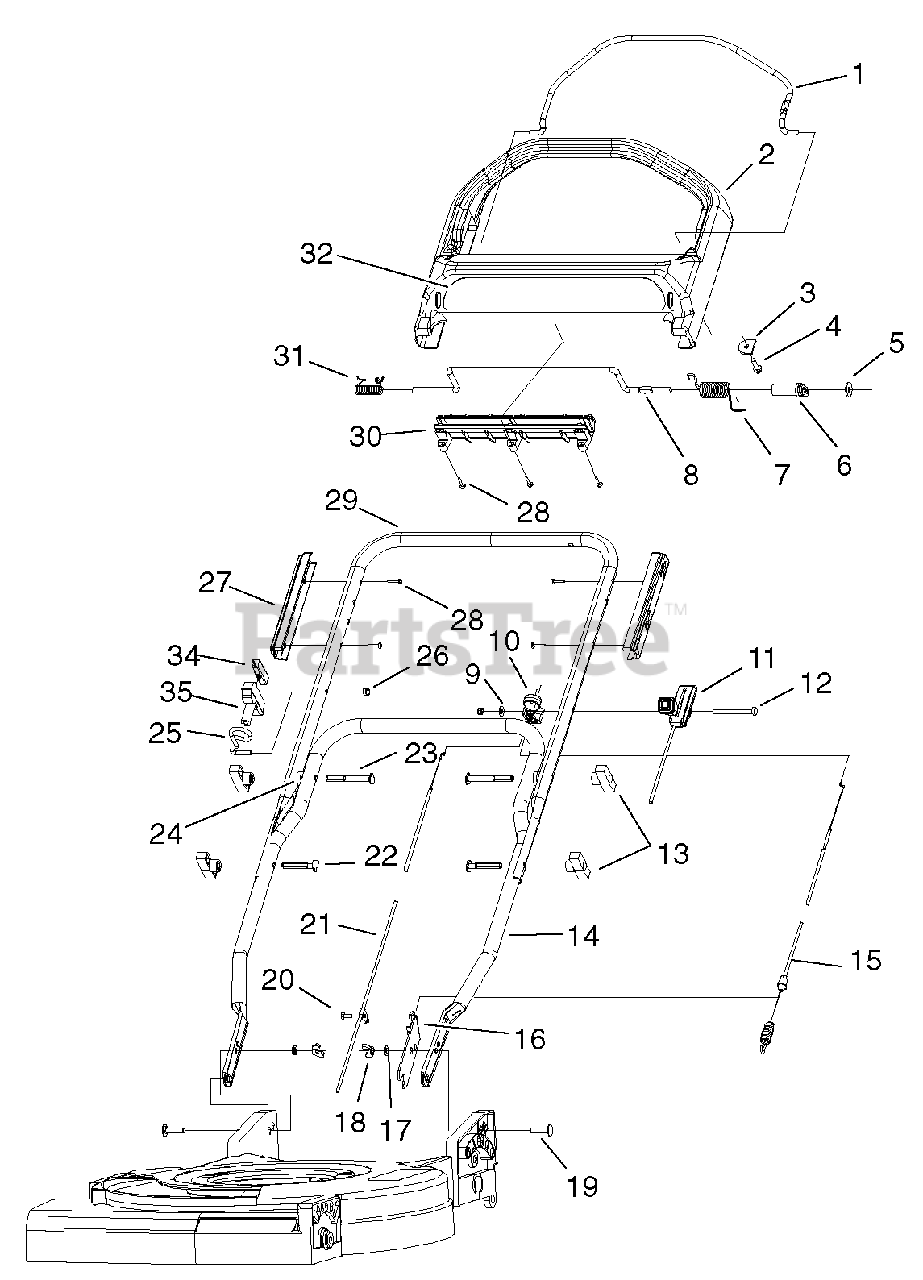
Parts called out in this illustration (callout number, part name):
1	BAIL-BRAKE
2	HANDLE-CONTROL
3	RETAINER-CABLE, BRAKE
4	SCREW-HWH
5	WASHER-FLAT
6	LEVER-TRACTION
7	SPRING-TORSION
8	BAR-CONTROL, TRACTION
9	WASHER-FLAT
10	ANCHOR-CABLE
11	CABLE - THROTTLE
12	SCREW-HH
13	KNOB-HANDLE
14	HANDLE-LOWER
15	CABLE-TRACTION
16	BRACKET-CABLE, TRACTION
17	WASHER-LOCK
19	SCREW-CARR
20	SCREW-TAPTITE
21	CABLE-BRAKE, FLYWHEEL
23	SCREW-HANDLE
24	SPACER-HANDLE
25	GUIDE-ROPE
26	NUT-LOCK, NI
27	GUIDE-HANDLE, CONTROL
28	SCREW-PPH
29	HANDLE-UPPER
30	RETAINER-CONTROL ROD, TRACTION
31	SPRING-TORSION, RH
32	DECAL-HANDLE
34	CLIP-STARTER
35	HANDLE-START
